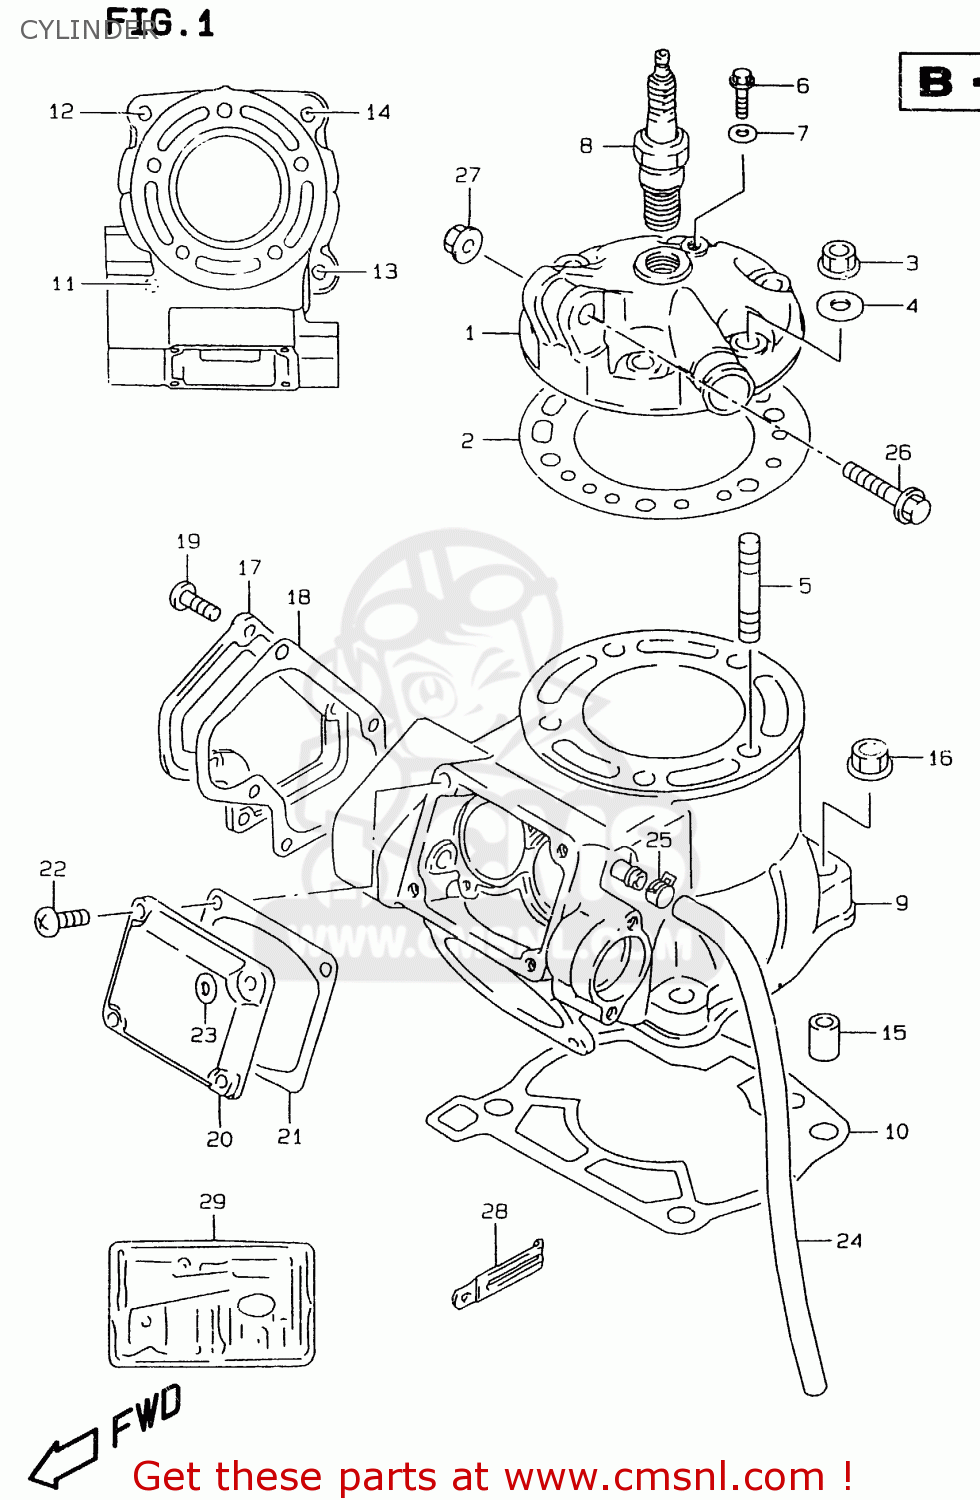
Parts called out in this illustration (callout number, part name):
1	HEAD,CYLINDER
2	GASKET,CYLINDER HEAD
3	NUT
4	WASHER(8.5X19X2.3)
5	BOLT,STUD
6	UNION
7	GASKET(6.2X11X1).2 (NAS)
8	SPARK PLUG BR9EV
9	CYLINDER SET
10	GASKET,CYLINDER (NAS)
11	STUD 10X30
12	STUD BOLT
13	STUD BOLT (L:40)
14	BOLT,STUD
15	PIN(13X10.4X20)
16	NUT
17	COVER,CYLINDER NO.1
18	GASKET,CYL COVER NO.1 (NAS)
19	BOLT
20	COVER,CYLINDER NO.2
21	GASKET,CYLINDER COVER NO.2 (NAS)
22	SCREW
23	GASKET(5.3X9.3X1.2) (NAS)
24	HOSE
25	CLIP
26	BOLT(8X45)
27	NUT
28	CLAMP(L:45)
29	GASKET SET (NAS)
